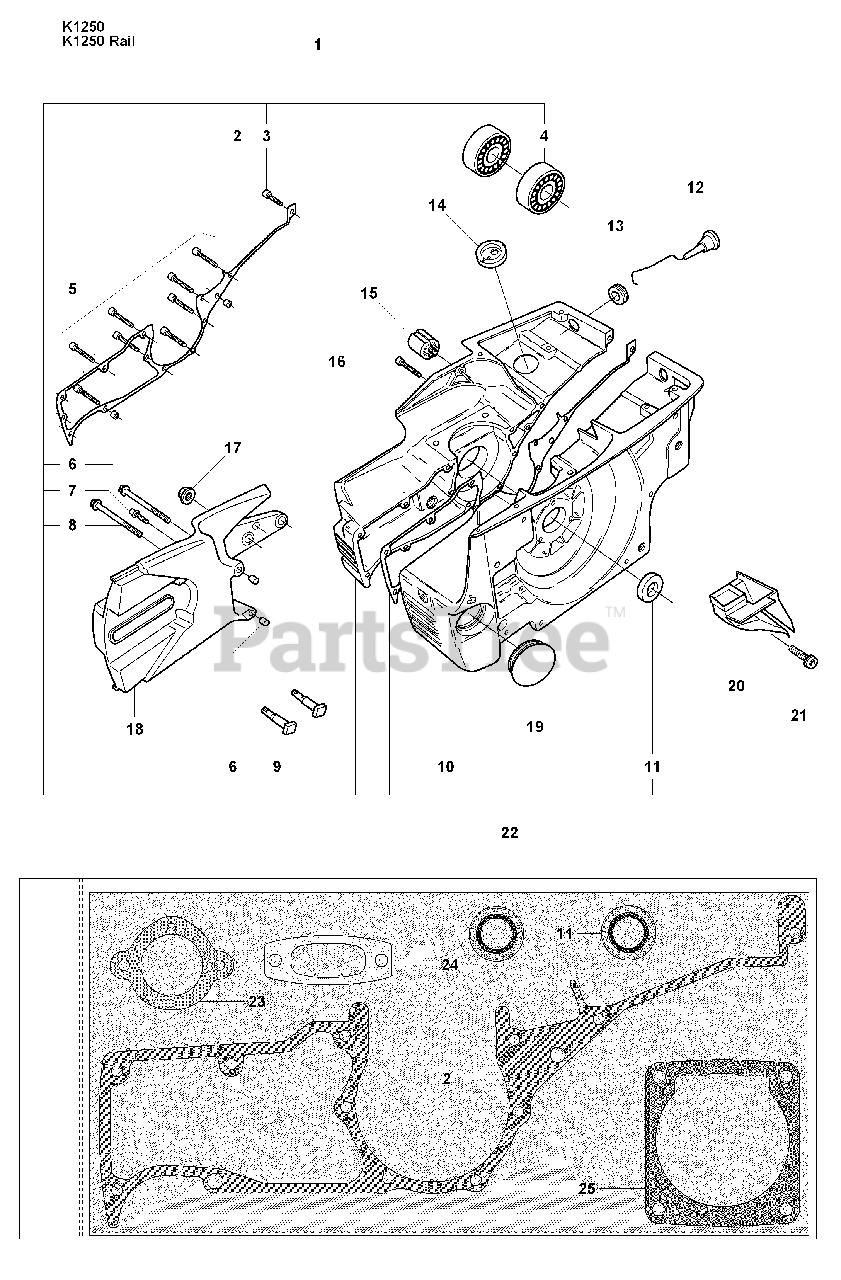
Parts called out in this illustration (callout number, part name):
1	CRANKCASE
2	CRANKCASE GASKET
3	SCREW
4	BALL BEARING
5	SCREW
6	GUIDE BUSHING
11	SEALING RING
12	CHOKE CONTROL
15	VIB.INSULATOR
17	NUT FLANGE
18	CUTTER ARM
20	AIR NOZZLE
21	SCREW
22	GASKET KIT
23	GASKET
24	GASKET MUFFLER
